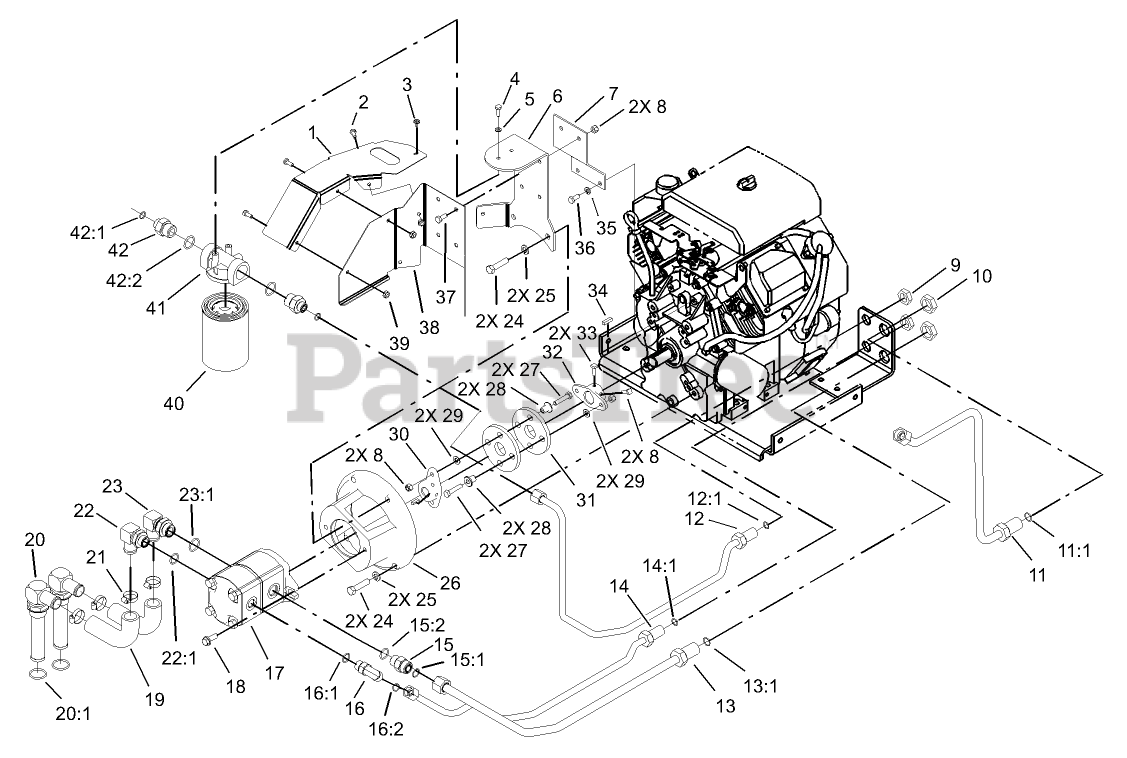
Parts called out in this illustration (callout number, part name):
1	SHIELD-HEAT
2	SCREW-HH
3	SCREW
4	SCREW-HH
5	WASHER-LOCK
6	BRACKET-SUPPORT, OIL FILTER
7	BRACKET-SUPPORT, OIL FILTER
8	NUT-LOCK, NI
9	NUT-BULKHEAD
10	NUT-LOCK, BULKHEAD
11	HYD TUBE ASM
11:1	O-RING
12	HYD TUBE ASM
12:1	O-RING
13	HYD TUBE ASM
13:1	O-RING
14	HYD TUBE ASM
14:1	O-RING
15	FITTING-STRAIGHT
15:1	O-RING
15:2	O-RING
16	FITTING-ELBOW-90 DEG
16:1	O-RING
16:2	O-RING
17	PUMP-GEAR, HYD
18	SCREW-HHF
19	HOSE-SUCTION, FORMED
20	STRAINER FITTING ASM
20:1	O-RING
21	CLAMP-HOSE
22	STEM-HOSE, 90 DEG
22:1	O-RING
23	FITTING-HYD, 90 DEG
23:1	O-RING
24	SCREW-HH
25	WASHER-LOCK
26	Mount-Pump
27	SCREW-HH
28	SPACER
29	WASHER-PLAIN
30	HUB-PUMP
31	COUPLING-RUBBER
32	HUB-ENGINE
33	SCREW-SQH
34	KEY-SQUARE
35	WASHER-LOCK
36	SCREW-HH
37	SCREW-HH
38	SHIELD-HEAT, FILTER
39	NUT-LOCK, NI
40	FILTER-OIL
41	HEAD-FILTER
42	FITTING-STR
42:1	O-RING
42:2	O-RING
